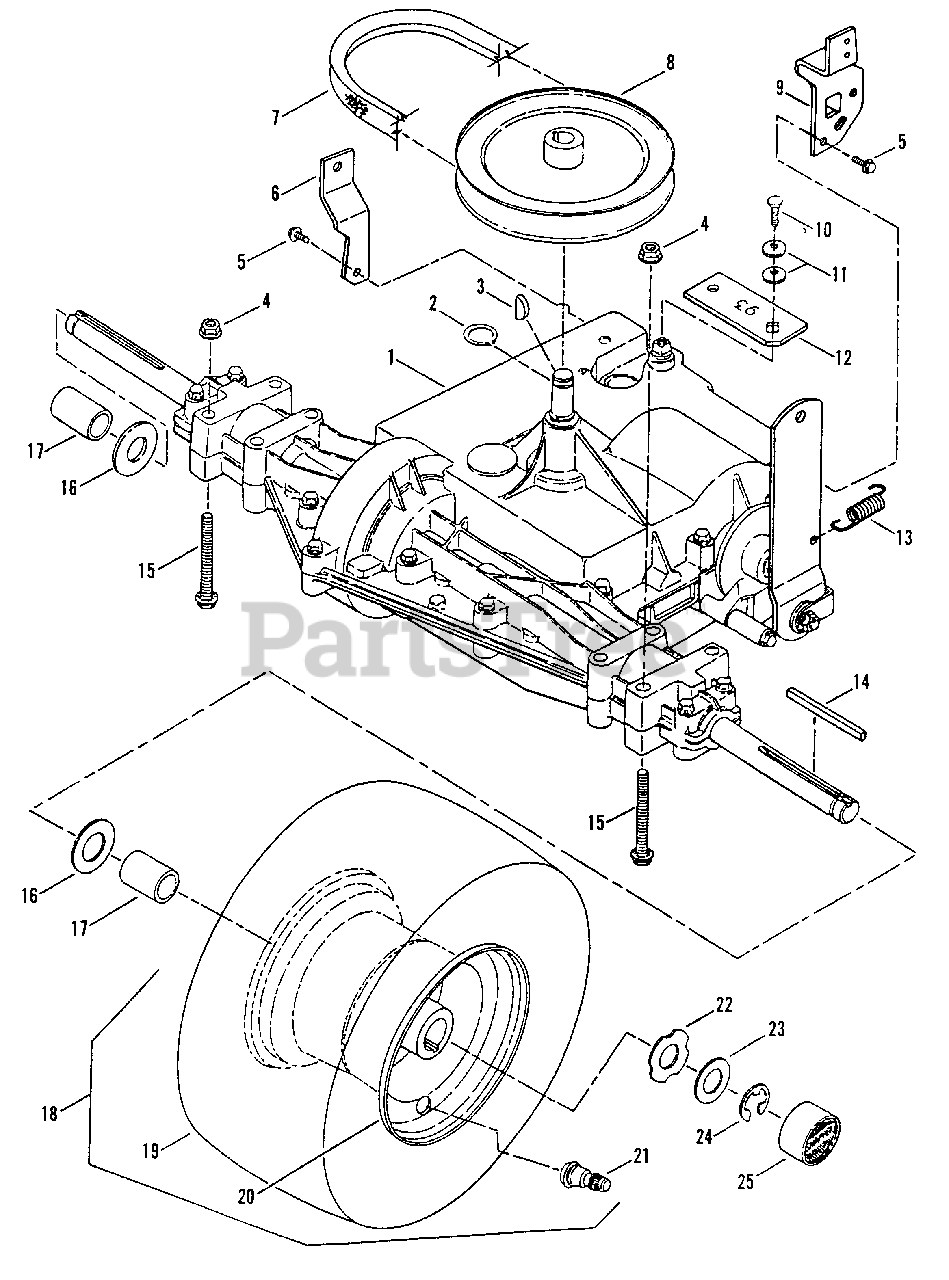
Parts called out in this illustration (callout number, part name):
1	TRANSAXLE, Gear Drive, Peerless Model 930, 5-Speed
2	RING, Retaining
3	KEY, Woodruff, 3/16 x 3/4", No. 9
4	NUT, 5/16-18 Hex Flange Lock, Grade 5
5	SCREW, 5/16-18 x 5/8" Hex Washer Head, Self-Tapping
6	BRACKET, Torque
7	BELT, Traction Drive, 97.75" EL
8	PULLEY, Drive
9	BRACKET, Axle/Spool
10	BOLT, 1/4-28 x 5/8" Hex Head, Grade 8
11	WASHER, 1/4" Bellville
12	ARM, Shift Link Lever
13	SPRING, Brake Return
14	KEY, Square, 3/16 x 3/16 x 2 1/2"
15	BOLT, 5/16-18 x 2-1/4" Hex Flange Lock
16	WASHER, Flat 3/4" I.D. x 1-5/8" O.D.
18	ASSEMBLY, Rear Tire & Rim
19	TIRE, 18 x 7.50
20	RIM, 8 x 5.375
21	VALVE, Air (Snap-in)
22	WASHER, Hub-Cap Retaining
23	WASHER, Flat, .3/4" I.D. x 1-5/16" O.D.
24	RING, Retaining
25	HUB-CAP
